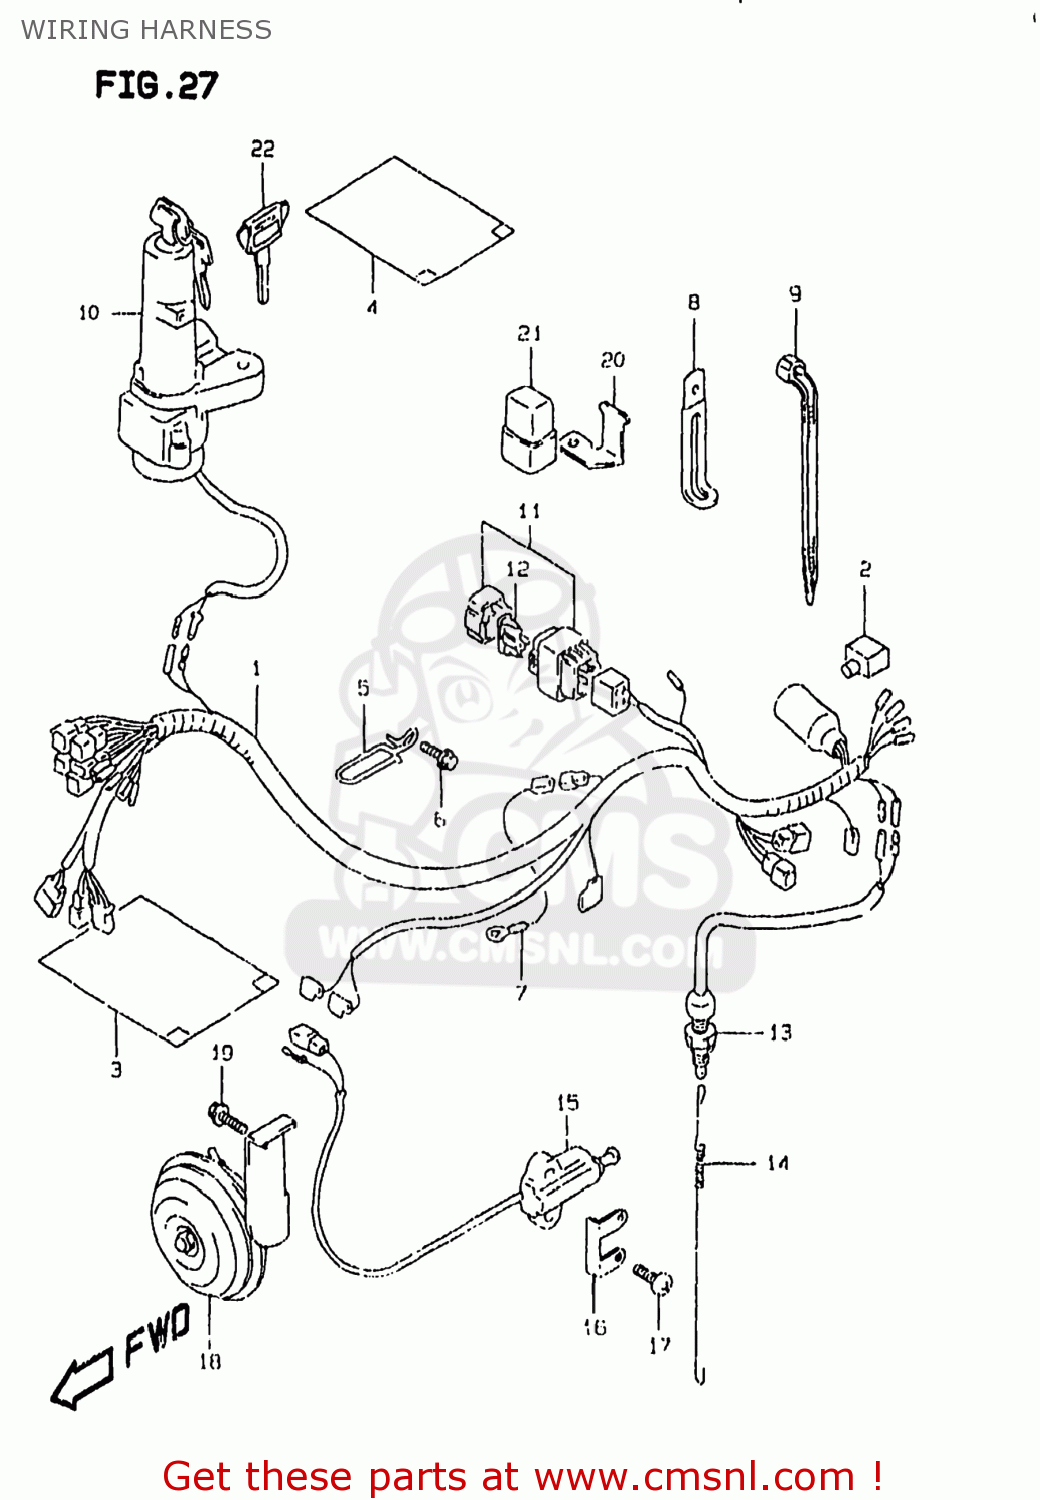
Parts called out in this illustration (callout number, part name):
1	HARNESS,WIRING
2	CAP,BATTERY PLUS
3	COVER,WIRING HARNESS
4	COVER,WIRING HARNESS
5	GUIDE,WIRING HARNESS
6	BOLT
7	WIRE,REGULATOR EARTH LEAD
8	CLAMP(L:80)
9	CLAMP(L:33)
10	SWITCH ASSY,IGNITION
11	BOX ASSY,FUSE
12	FUSE(20A)
13	SWITCH ASSY,STOP LAMP
14	SPRING
15	SWITCH ASSY,SIDE STAND WARNING
16	PROTECTOR,SIDE STAND SWITCH
17	SCREW
18	HORN ASSY
19	BOLT
20	BRACKET,FUSE
21	RELAY ASSY
22	KEY,BLANK(TYPE:C)
